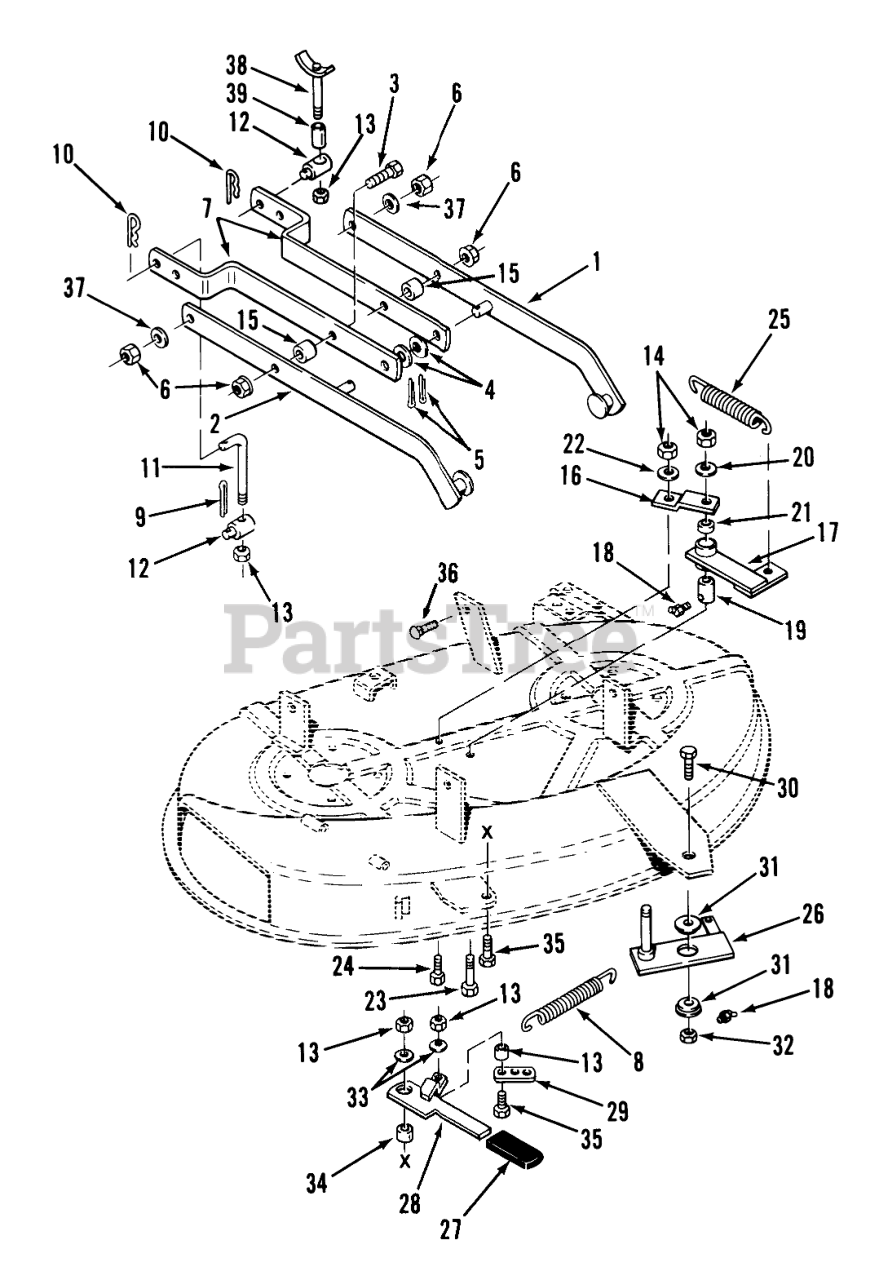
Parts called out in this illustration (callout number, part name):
1	Draft Bar LH
2	Draft Bar RH
3	Bolt
4	WASHER
5	PIN-4
6	LOCKNUT-FLANGE
7	Bar-Leveler
8	Spring
9	Cotter Pin
10	Hairpin
11	ROD-LIFT
12	Trunion
13	NUT
14	Nut
15	SPACER
16	Strap
17	Arm-Idler
18	Zerk
19	SPACER-2.0 LG R
20	Washer
21	BUSHING
22	WASHER 5/16 SAE
23	Pin-Cotter
24	Bolt
25	SPRING
26	Countershaft
28	Lever
29	Link
30	Bolt
31	BUSHING
32	Nut
33	WASHER
34	SPACER
35	Bolt
36	Bolt
37	SPACER
38	WLDMT-HANGER ROD
39	SPACER .375 ID X 1.6
